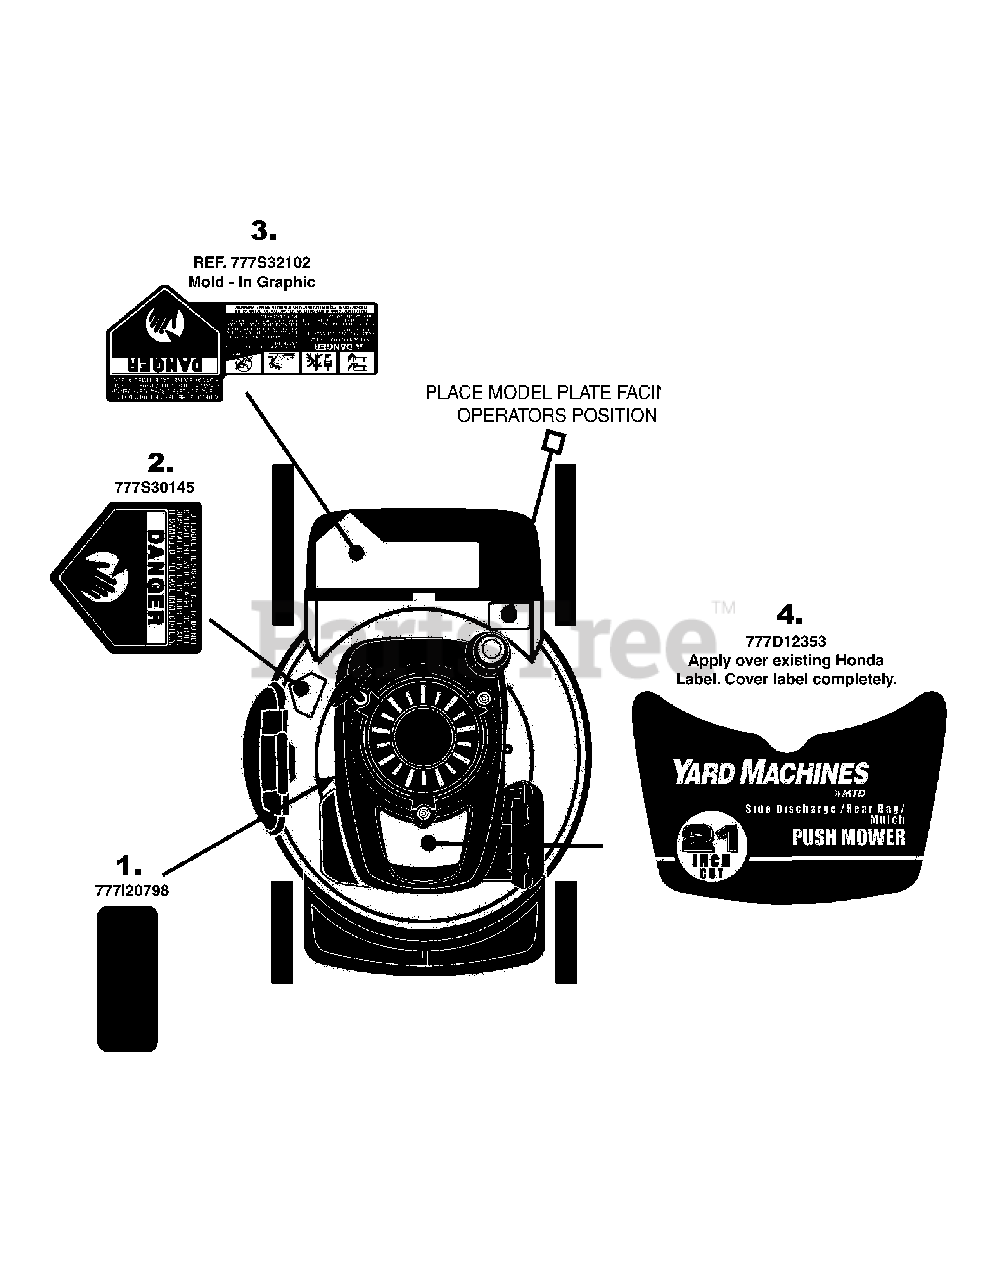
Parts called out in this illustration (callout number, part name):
1	LABEL-SHROUD
2	LABEL
3	LABEL
4	LABEL-MOWER SHROUD YARD MACH 21"
